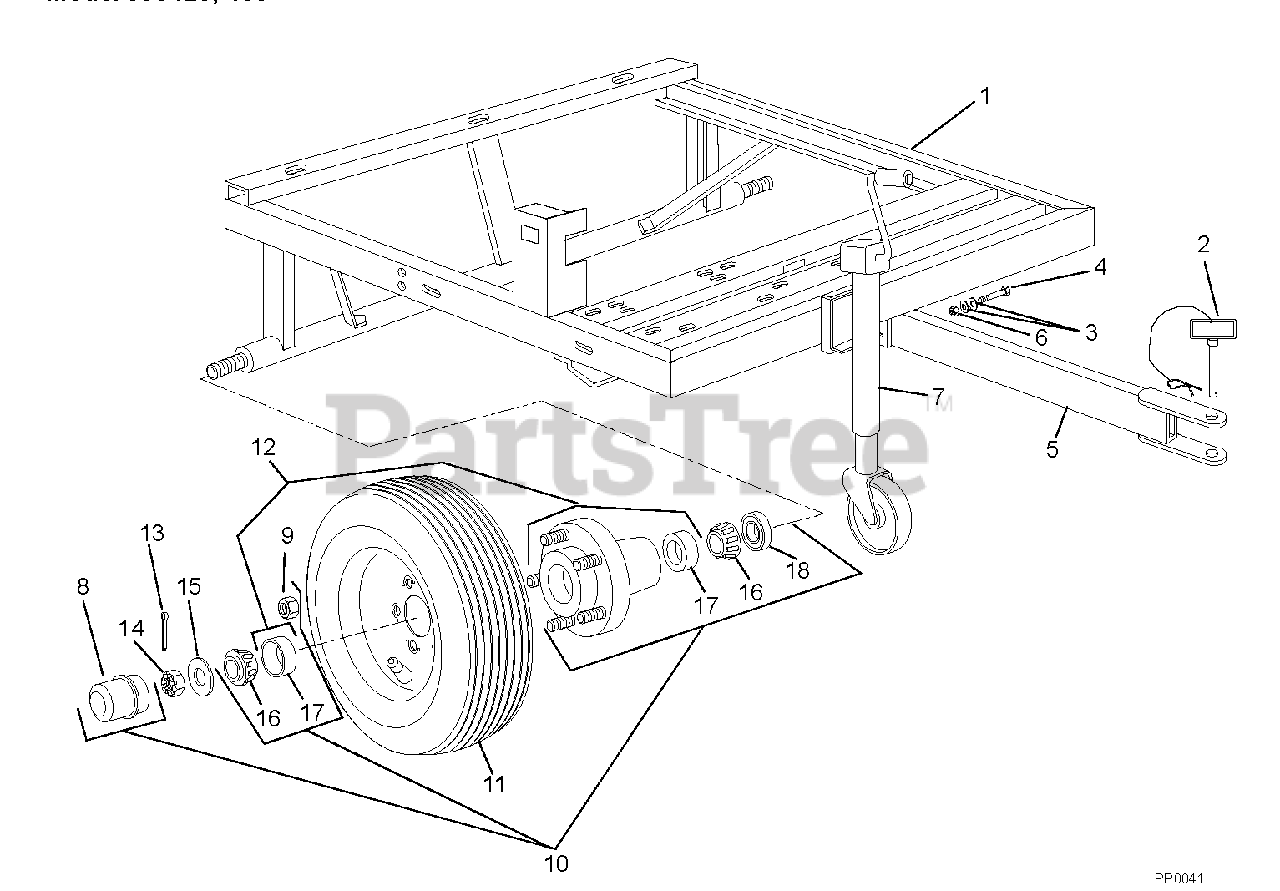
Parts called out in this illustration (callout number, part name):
1	Weldment, Frame
2	Pin, Hitch 1 x 4.50"
3	Washer, Flat Steel .625
4	Cap Screw, Hex Head .625-11 x 3
5	Weldment, Tongue
6	Nut, Flange Lock .625-11
7	Jack Assembly with Swivel Wheel
8	Cap, Hub
9	Nut, Hex Hub .50-20 UNF 2B-45D
10	Assembly, Hub 5-Bolt (Contains Items 8, 9, 12, 16 and 18)
11	Assembly, Tire & Wheel 18 x 8.5 x 8
12	Hub With Bolts (Includes Item 17)
13	Pin, Cotter .125 x 1.25
14	Nut, Hex .75-16 Castellated
15	Washer .75 Keyed
16	Cone, Bearing
17	Cup, Bearing
